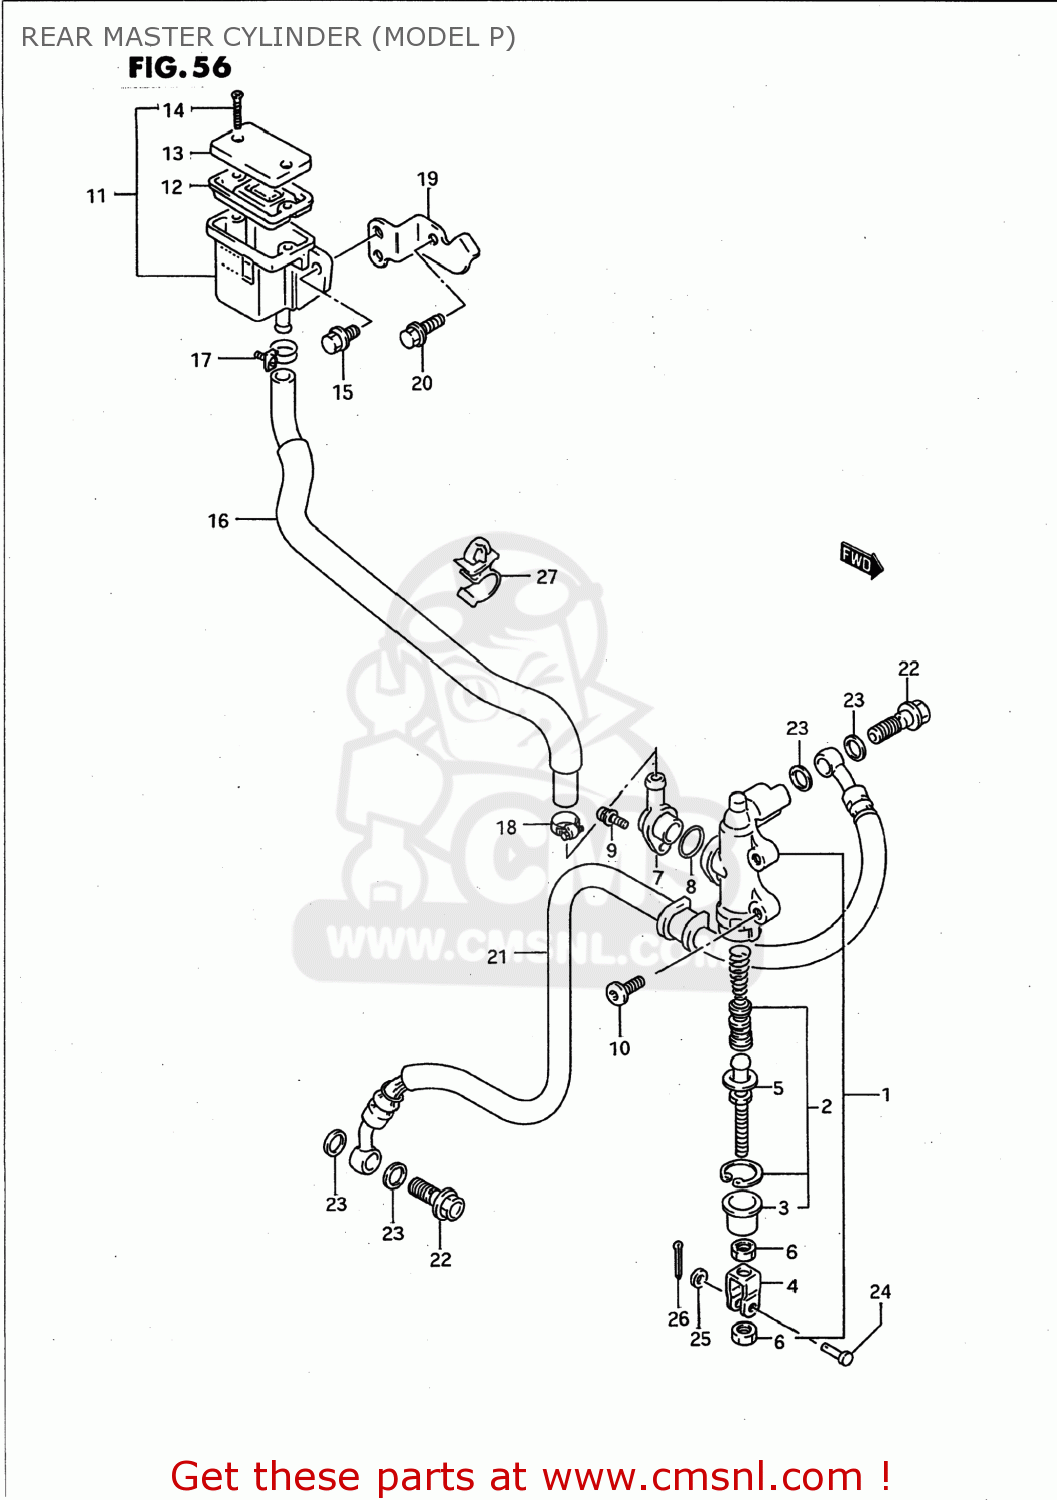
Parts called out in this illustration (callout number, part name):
1	CYLINDER ASSEMBLY,REAR MASTER
2	PISTON/CUP SET
3	BOOT
4	YOKE
5	ROD,PUSH
6	NUT
7	CONNECTOR
8	O RING
9	SCREW
10	SCREW(8X22)
11	TANK ASSY,RESERVOIR
12	DIAPHRAGM
13	CAP
14	SCREW
15	BOLT
16	HOSE,RESERVOIR TANK
17	CLAMP
18	CLAMP
19	PLATE,RESERVOIR TANK
20	BOLT 6X20
21	HOSE COMP,REAR BRAKE
22	BOLT UNION
23	WASHER(10X15X1.5)
24	PIN
25	WASHER
26	PIN
27	CLAMP
